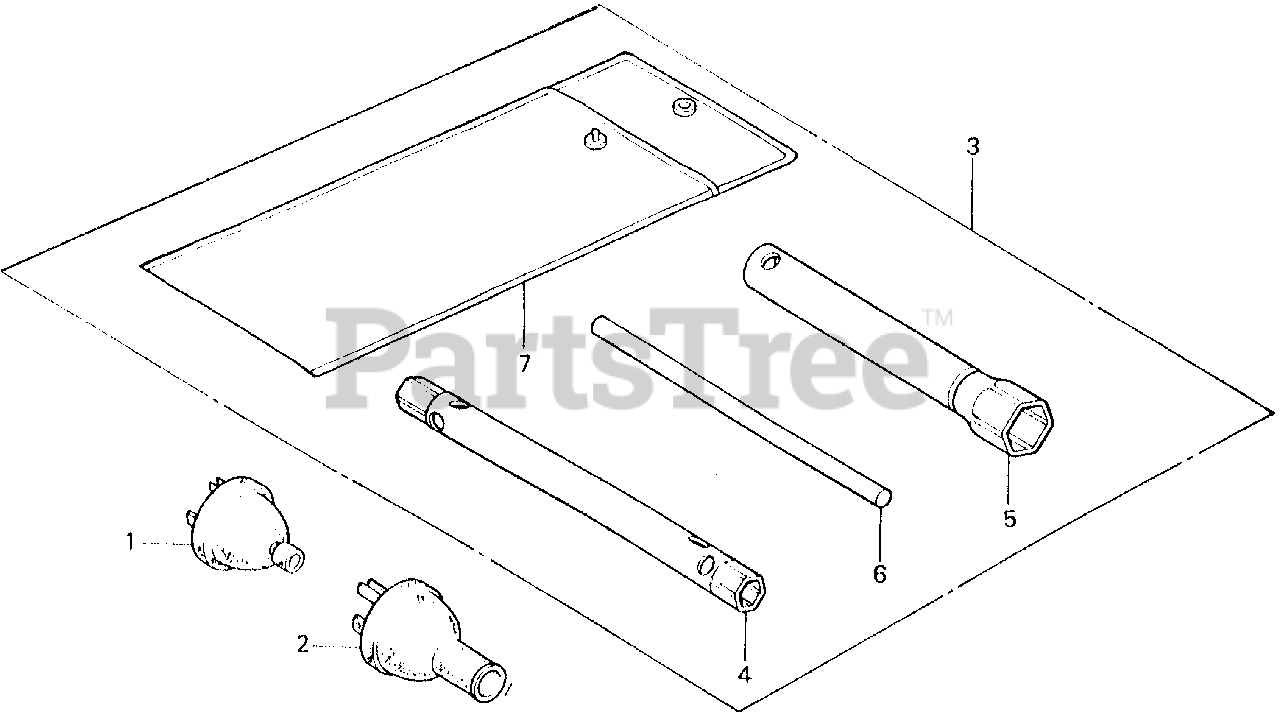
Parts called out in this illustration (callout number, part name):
1	PLUG ASSY., RECEPTACLE (30A 250V)
2	PLUG ASSY., RECEPTACLE (20A 250V)
3	TOOL KIT (NOT AVAILABLE)
4	WRENCH, BOX (10X12) (NOT AVAILABLE)
5	WRENCH, BOX (P21)
6	BAR A, HANDLE
